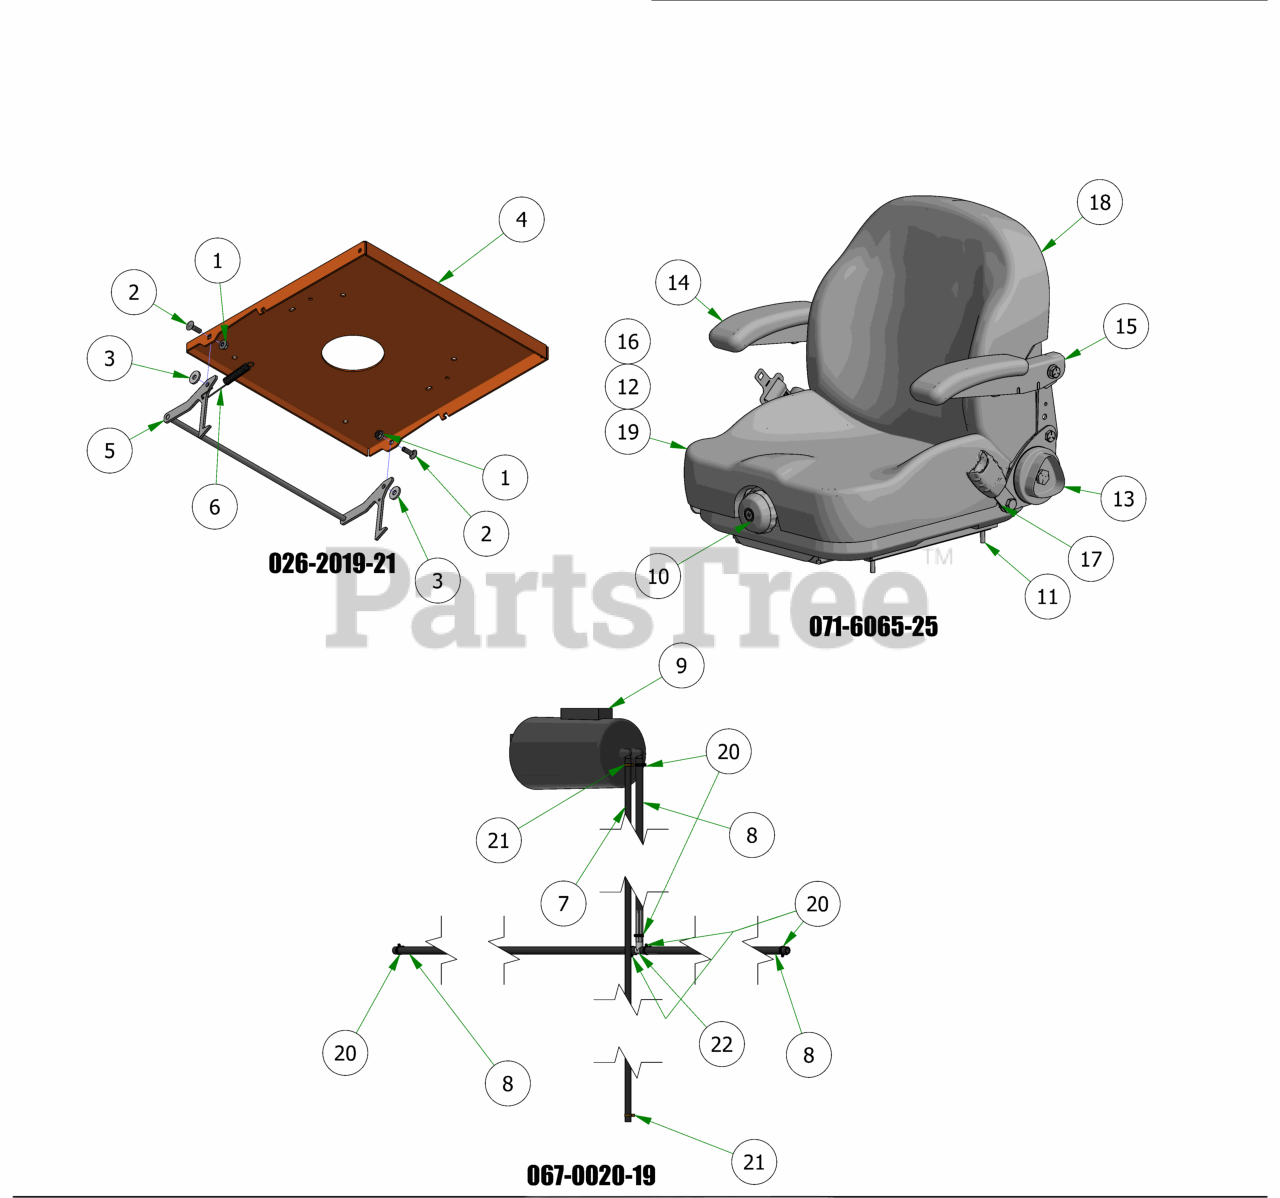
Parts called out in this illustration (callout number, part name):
1	5/16-18 NYLON INSERT FLANGE LOCKNUT ZINC
2	5/16-18 X 1 CARRIAGE BOLT (GR.8) ZINC
3	.360 ID X .983 OD X .120 THICK FLAT WASHER NYLON
4	R-SERIES SEAT PLATE
5	Seat Latch Rod Assembly
6	Brake Spring
7	3/16" Vinyl Tubing, 66" Long
8	1/4" Vinyl Tubing 38" Long
9	Carbon Canister
10	Weight Adjust Indicator Knob Assy
11	4" Single Locking Track Kit
12	Delta Plunger Switch - N.O.
13	Recliner Adjustment Knob-New
14	RH Armrest-Selfskin Front Adj
15	LH Armrest-Selfskin Front Adj
16	Bellows w/Hardware
17	2" Retractable Belt Kit w/Spacers
18	Back Cover, 2025 Suspension Seat
19	Cushion Cover, 2025 Suspension Seat
20	3/16 Vinyl Clamp
21	3/16" Vinyl Hose Clamp
22	fuel line T
